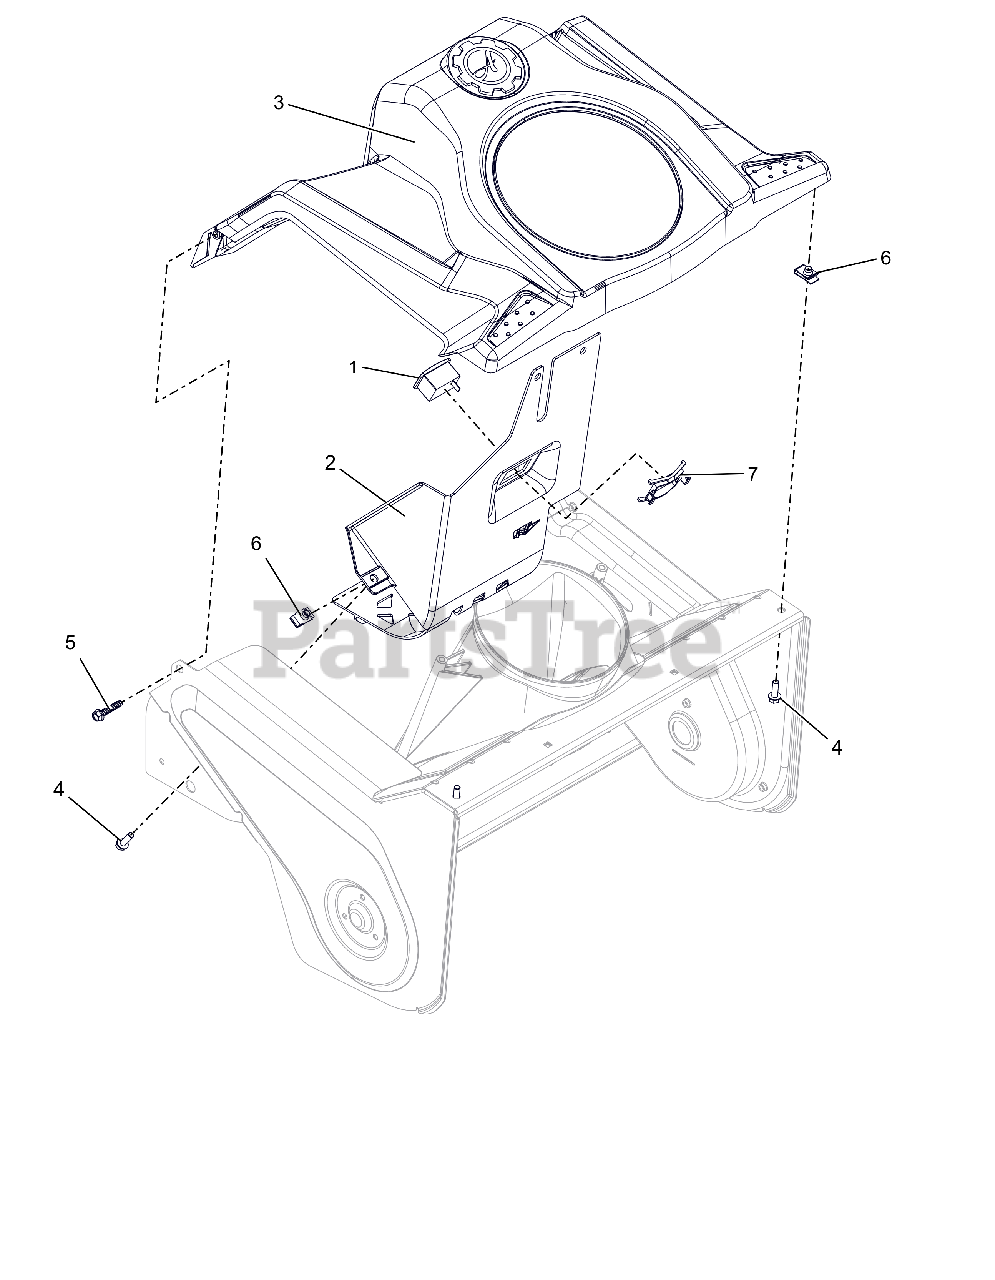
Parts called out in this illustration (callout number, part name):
1	METER, HOUR INDCTV RECOIL ENG
2	COVER, BACK
3	COVER, HOUSING - W/DECAL
4	BLT-HEX .25-20X.75 HWH YZ GR5
5	SCR-TAP .25-10X1.25 HWH YWZC
6	NUT-RTNR .25-20X.56
7	HOUR, METER - QUICK CLIP
